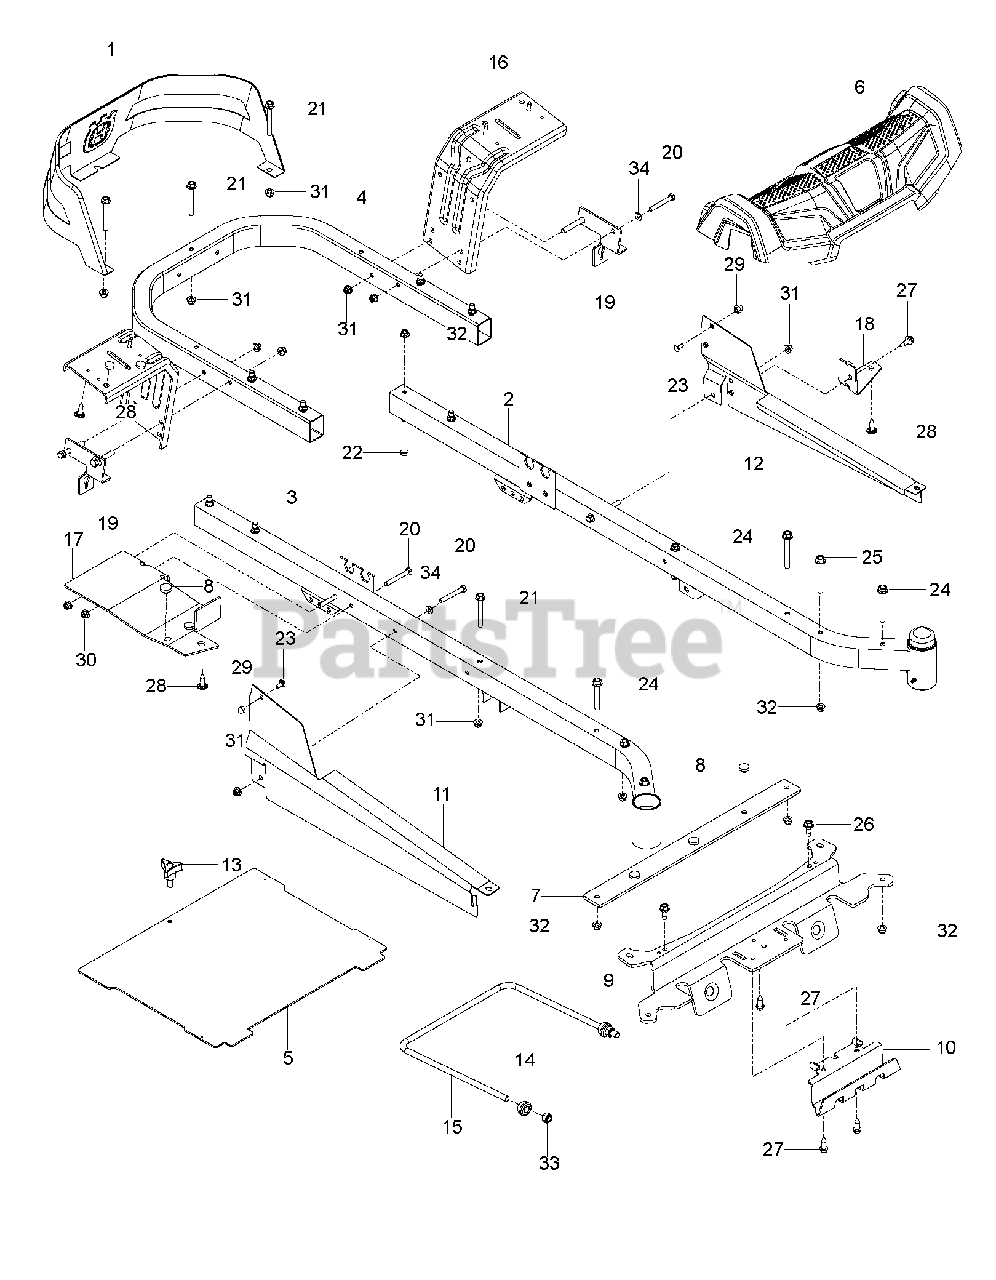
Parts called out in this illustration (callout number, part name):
1	GUARD.ENGINE.HUSQ.RZ.X498
2	FRAME, RT, ORANGE
3	FRAME, LT, ORANGE
4	TUBE.PNT.FRAME.RER.HUSQ.23".RZ
5	PLATE, FOOT W/DECALS RZ
6	COVER.FOOTREST.REFRESH.ASM
7	FOOTREST.PLATE.SUPPORT.X431
8	GROMMET.BUMPER
9	CROSS.PNT.MEMBER.BLK
10	SKID.PLATE.PNT.RZ.REF.SIVER
11	COVER.RAIL.RH.RZ.X668
12	COVER.RAIL.LH.RZ.X668
13	KNOB W/STUD
14	BUSHING SPHERICAL SUSP. FRONT
15	LINK, FRONT SUSP.
16	FENDER.SUPPORT.PNT.X431
17	SUPPORT.PNT.RH.CONSOLE.FRONT
18	SUPPORT.PNT.LH.CONSOLE.FRONT
19	BRKT ROD.BYPASS.EZT.X431
20	BOLT.FIN HEX 5/16-18UNC X2 1/4
22	BOLT.HEX.FIN.3/8-16 X 3.GR5
23	BOLT.CARRIAGE.5/16-18.7/16
24	HHFS 3/8-16 X 3 GRD 5 ZD
25	BOLT SHOULDER,FLANGED,3/8-16X3
26	BOLT.5/16-18.THRD.ROLL.SHOULDR
27	BOLT.5/16HEX.WHS.HD
28	SCREW.#10 X 0.750.BOS
29	NUT ACORN,FLANGED,5/16-18
30	NUT LOCK HEX FLANGE 5/16-18
31	5/16-18 NYLOC FLANGE NUT
32	NUT 3/8-16 HEX FLG NYLOC ZD
33	7/16-14 HEX NUT W/NYL RING ZD
34	WASHER - 15X7.3X1.6
